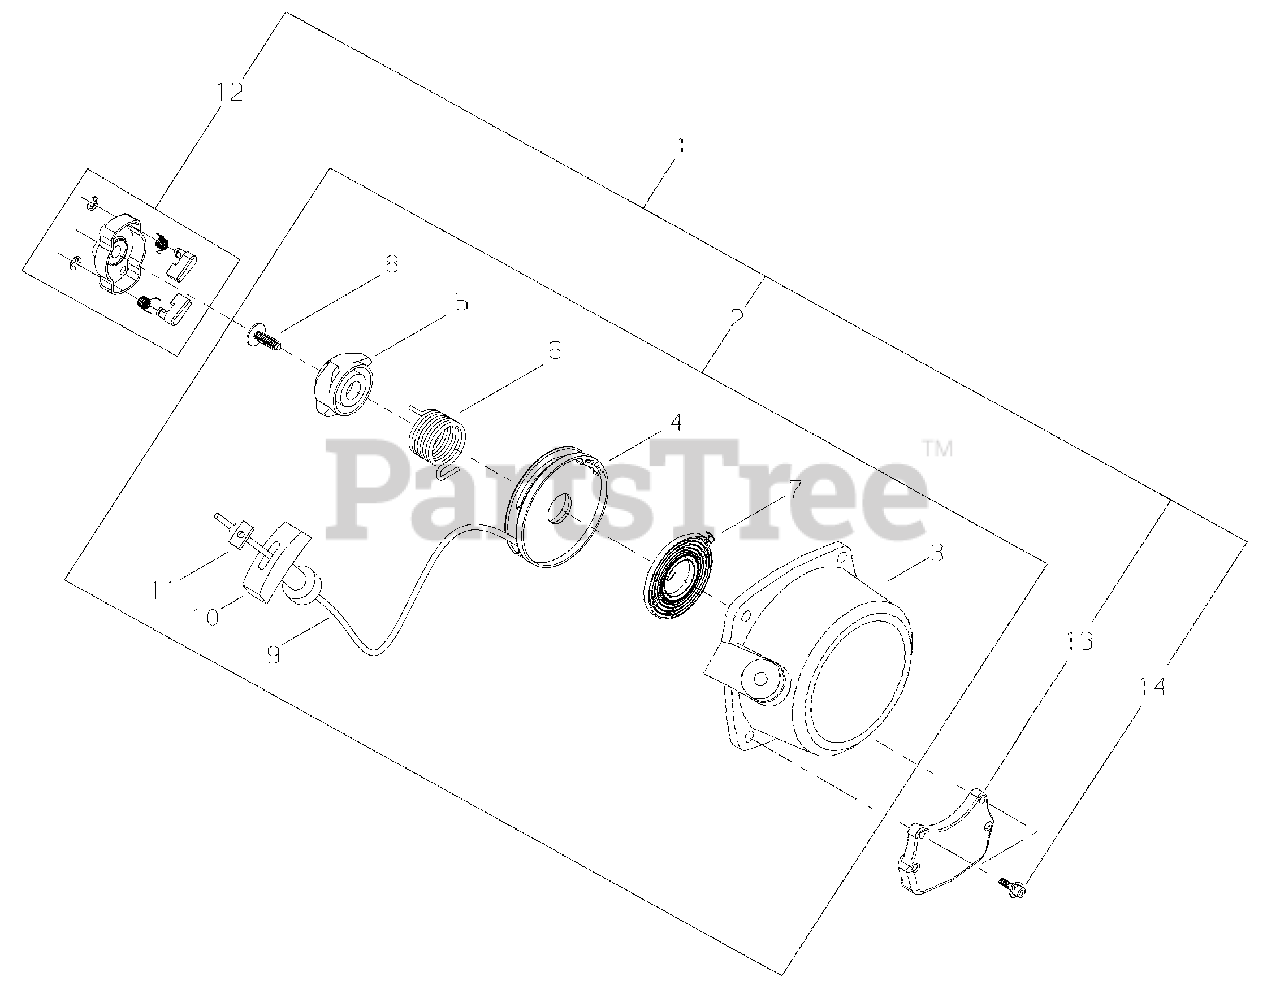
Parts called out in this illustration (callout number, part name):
1	SPRING ASSISTED RECOIL SET
2	STARTER ASSY, RECOIL
3	CASE, RECOIL STARTER
4	REEL, ROPE
5	CAM
6	SPRING, TORSION
7	SPRING, RECOIL
8	SCREW 5
9	ROPE, STARTER
10	GRIP, STARTER
11	RETAINER, ROPE
12	PULLEY, STARTER
13	BRACKET, FUEL TANK
14	BOLT M4×20
